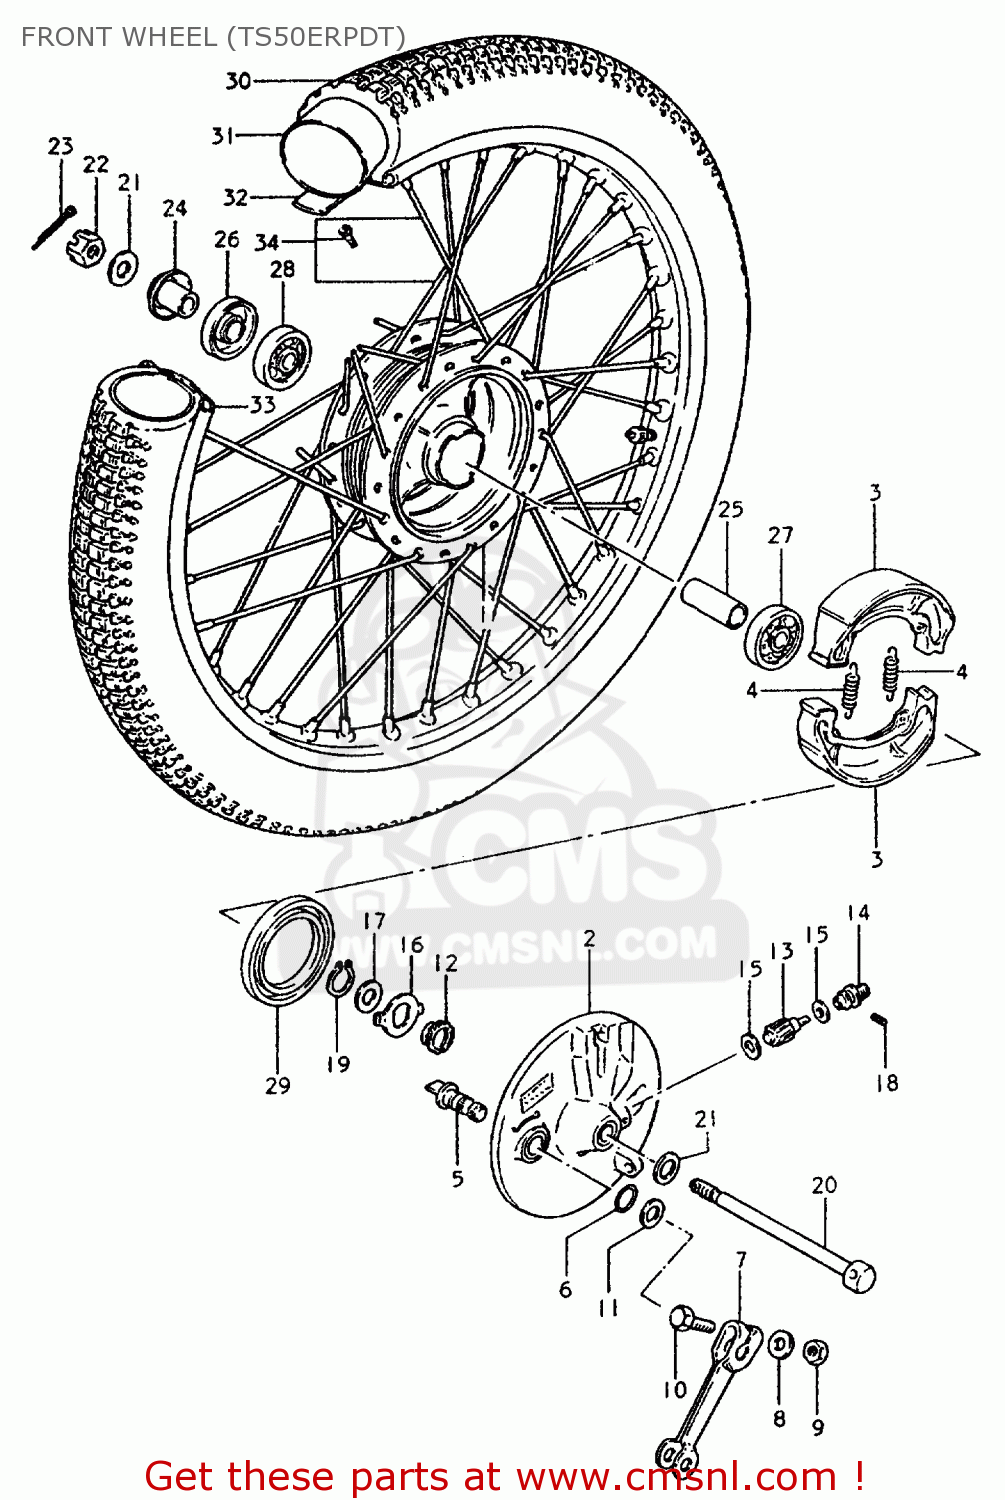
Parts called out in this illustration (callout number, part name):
1	HUB,FRONT
2	PANEL, FRONT HUB
3	SHOE,BRAKE
4	SPRING(L:34)
5	CAM,FRONT BRAKE
6	O-RING (D:2.4 ID:13.8)
7	LEVER,FR BRAKE CAM
8	WASHER
9	NUT
10	BOLT(6X33)
11	WASHER (14.5X22X1.6)
12	GEAR,SPEEDOMETER
13	PINION,SPEEDOMETER
14	BUSH,METER GEAR OUTER
15	WASHER (5.1X9X0.4)
16	DRIVER,SPEEDOMETER GEAR
17	WASHER(18.5X24X1)
18	SCREW
19	CIRCLIP
20	AXLE,FRONT
21	WASHER
22	NUT
23	PIN 20X20
24	SPACER,FRONT AXLE,RIGHT
25	SPACER (10.2X16X51)
26	SEAL,OIL(15X31X5)
27	BEARING
28	BEARING
29	OIL SEAL (43X58X7)
30	TIRE,FRONT
31	TUBE
32	PROTECTOR,WHEEL,INNER
33	RIM, WHEEL
34	SPOKE ASSY
